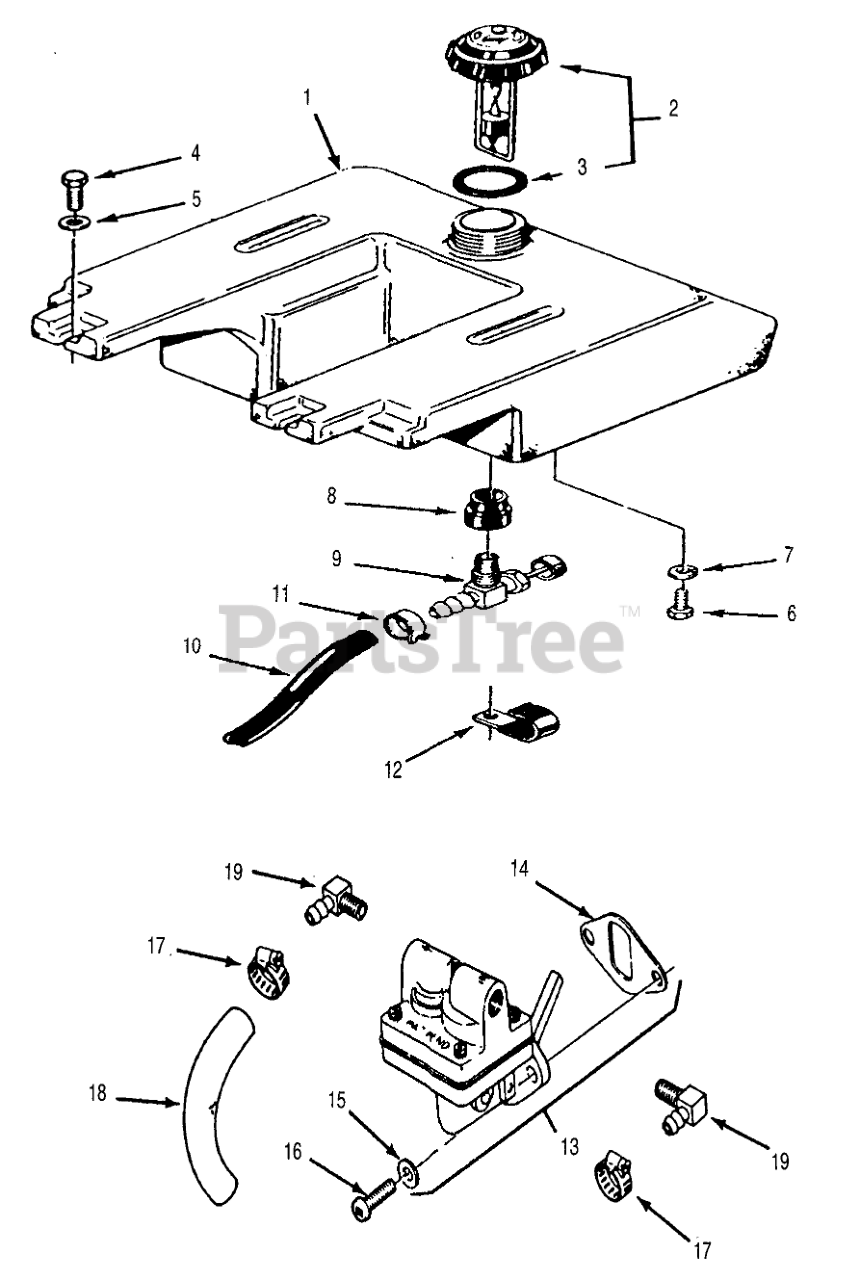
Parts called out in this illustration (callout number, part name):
1	TANK-FUEL
2	Fuel Cap & gauge (Includes Item 19)
3	GASKET-GAS CAP
4	Bolt
5	Washer
6	Bolt
7	Lockwasher
8	BUSHING
9	VALVE-FUEL
10	Fuel Line 62
11	Clamp
12	Clamp
13	Fuel Pump Assy (Includes items 30 & 31)
14	Gasket-Fuel Pump
15	Washer
16	Screw-F.H.
17	Clamp
18	Line-Fuel
19	Connector
